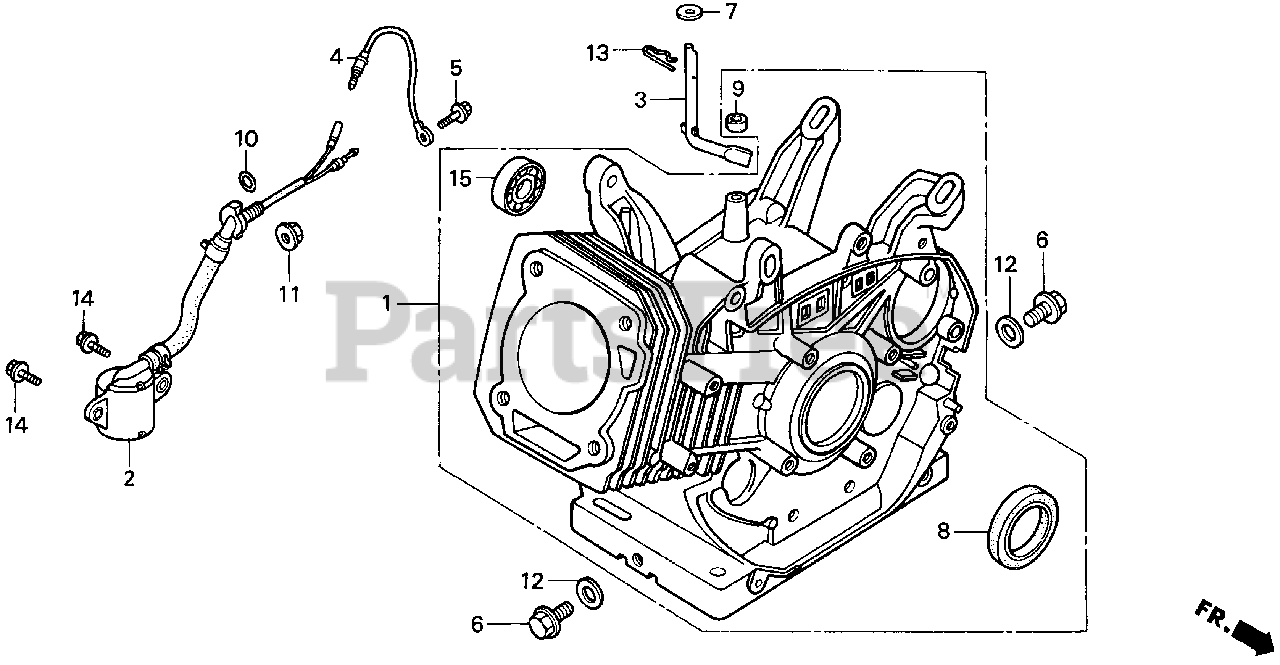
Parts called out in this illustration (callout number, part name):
1	CYLINDER ASSY.
1	CYLINDER ASSY. (ALERT)
2	SWITCH ASSY., OIL LEVEL
3	SHAFT, GOVERNOR ARM
4	SUB-HARNESS
5	BOLT, FLANGE (6X12) (CT200)
6	BOLT, DRAIN PLUG
7	WASHER (8.2X17X0.8)
8	OIL SEAL (35X52X8)
9	OIL SEAL (8X14X5)
10	O-RING (13.5X1.5) (ARAI)
11	NUT, FLANGE (10MM)
12	WASHER, DRAIN PLUG (12MM)
13	PIN, LOCK (8MM)
13	PIN, LOCK (10MM)
14	BOLT, FLANGE (6X12)
15	BEARING, RADIAL BALL (6202)
16	ALERT UNIT, OIL
17	BOLT, FLANGE (6X12) (CT200)
